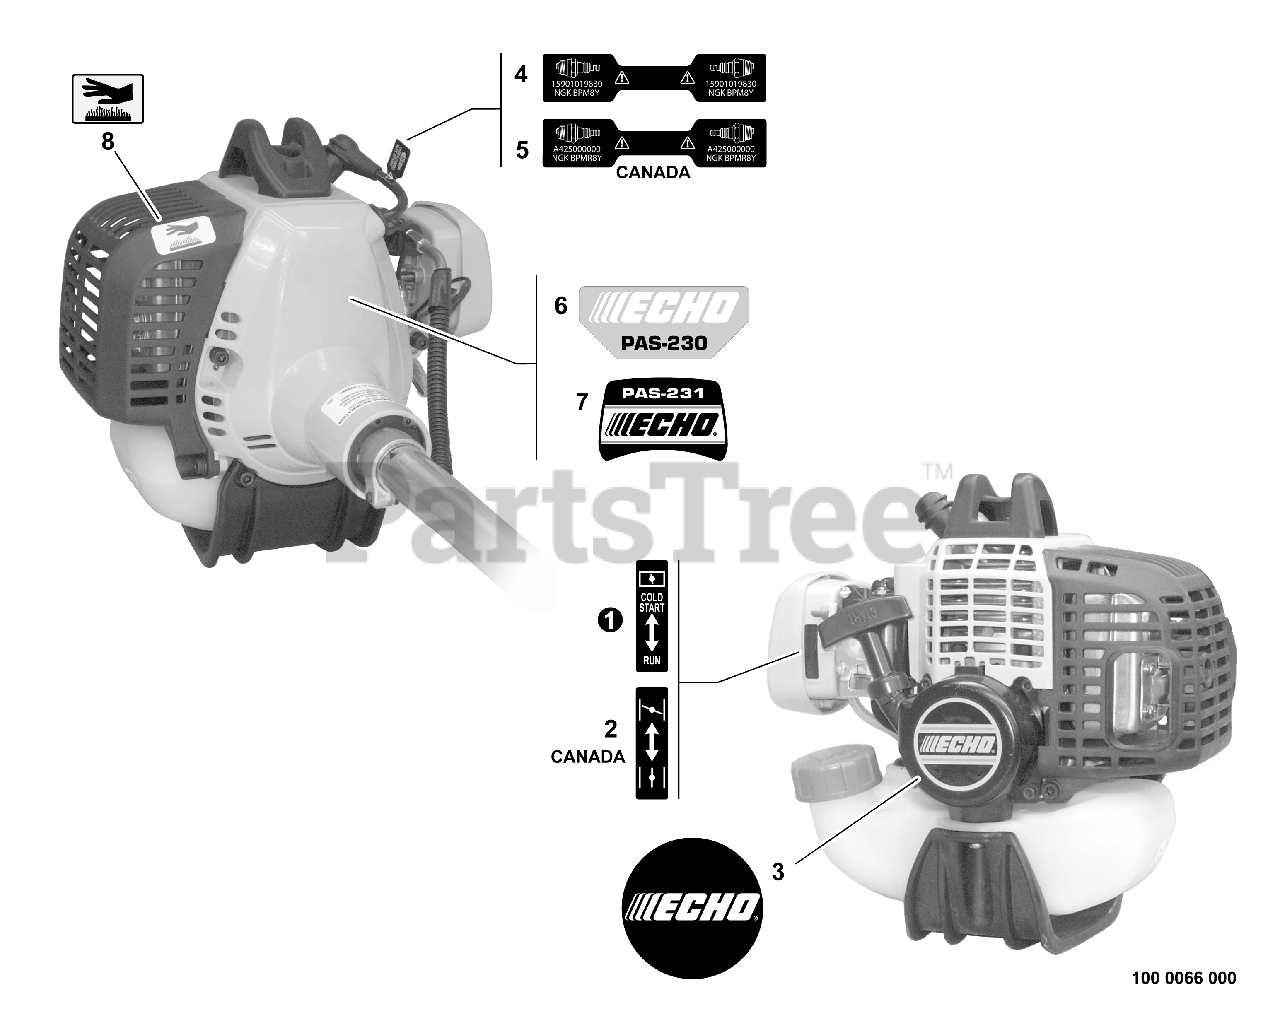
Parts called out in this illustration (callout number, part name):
1	LABEL - CHOKE
2	LABEL - CHOKE
3	LABEL - ECHO
4	LABEL - SPARK PLUG -- BPM-8Y
5	LABEL - SPARK PLUG -- BPMR-8Y
6	LABEL - MODEL PAS-230
7	LABEL - MODEL PAS-231
8	LABEL - HOT SURFACE
